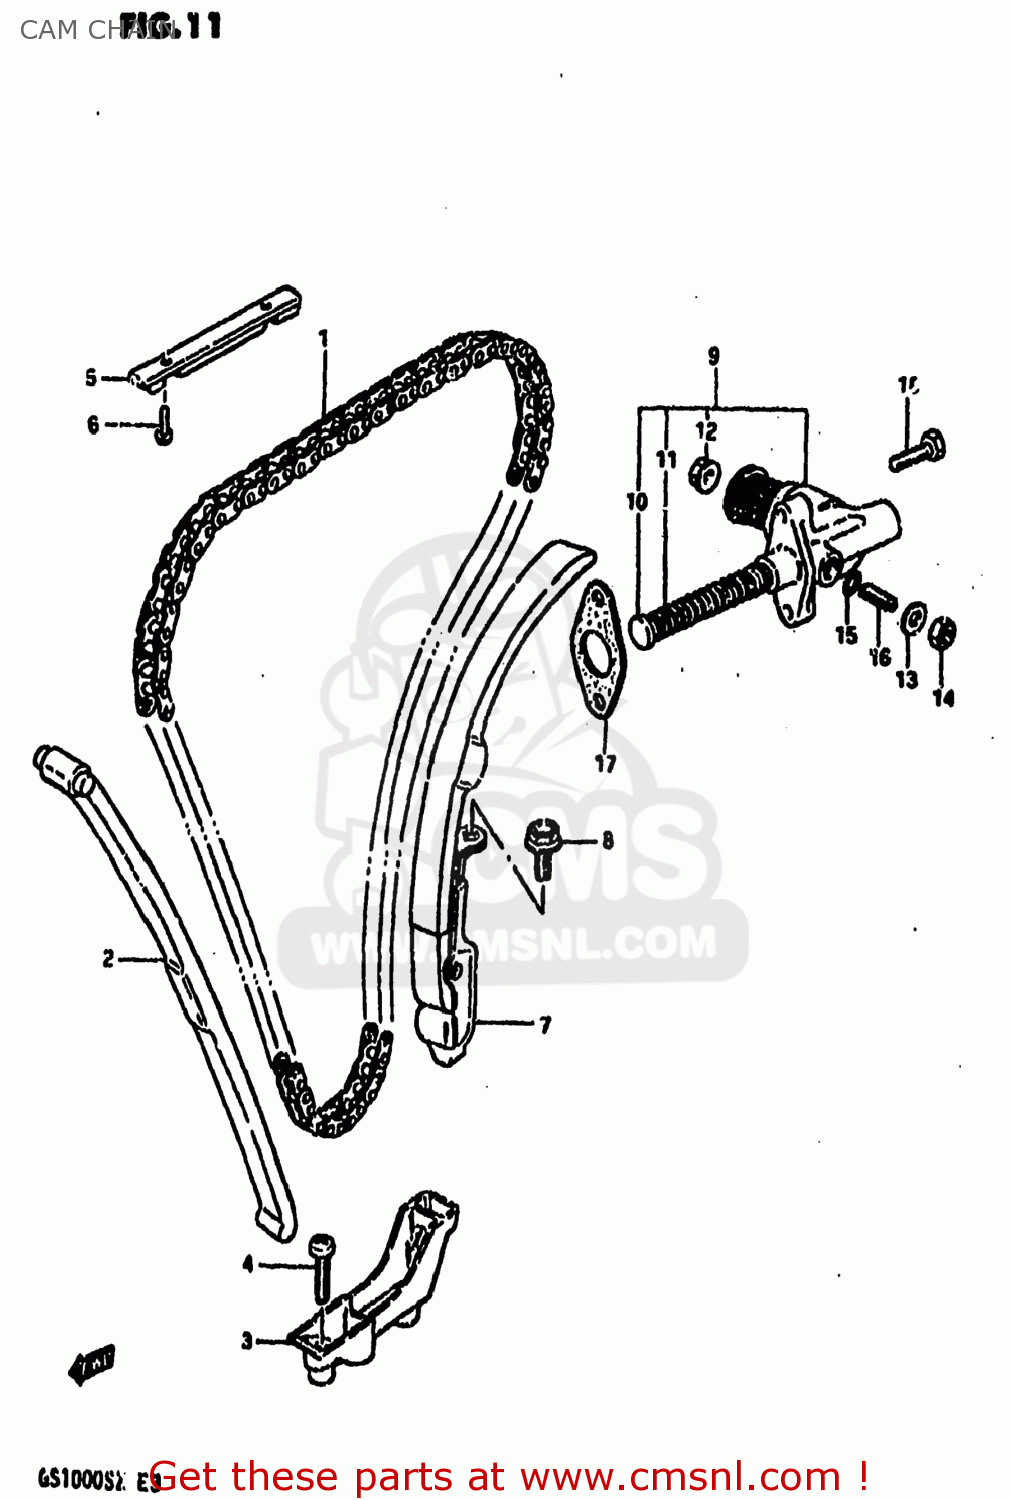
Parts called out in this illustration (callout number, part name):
1	CHAIN,CAMSHAFT DRIVE
2	GUIDE,CAM CHAIN NO.1
3	HOLDER,CAM CHAIN GUIDE
4	SCREW
5	GUIDE,CAM CHAIN
6	SCREW
7	TENSIONER,CAM CHAIN
8	BOLT
9	ADJUSTER ASSEMBLY,TENSIONER
10	ROD,PUSH
11	SPRING
12	SCREW
13	WASHER
14	NUT
15	O-RING
16	NUT
17	GASKET,TENSIONER ADJUSTER (MCA)
18	SCREW (6X25)
